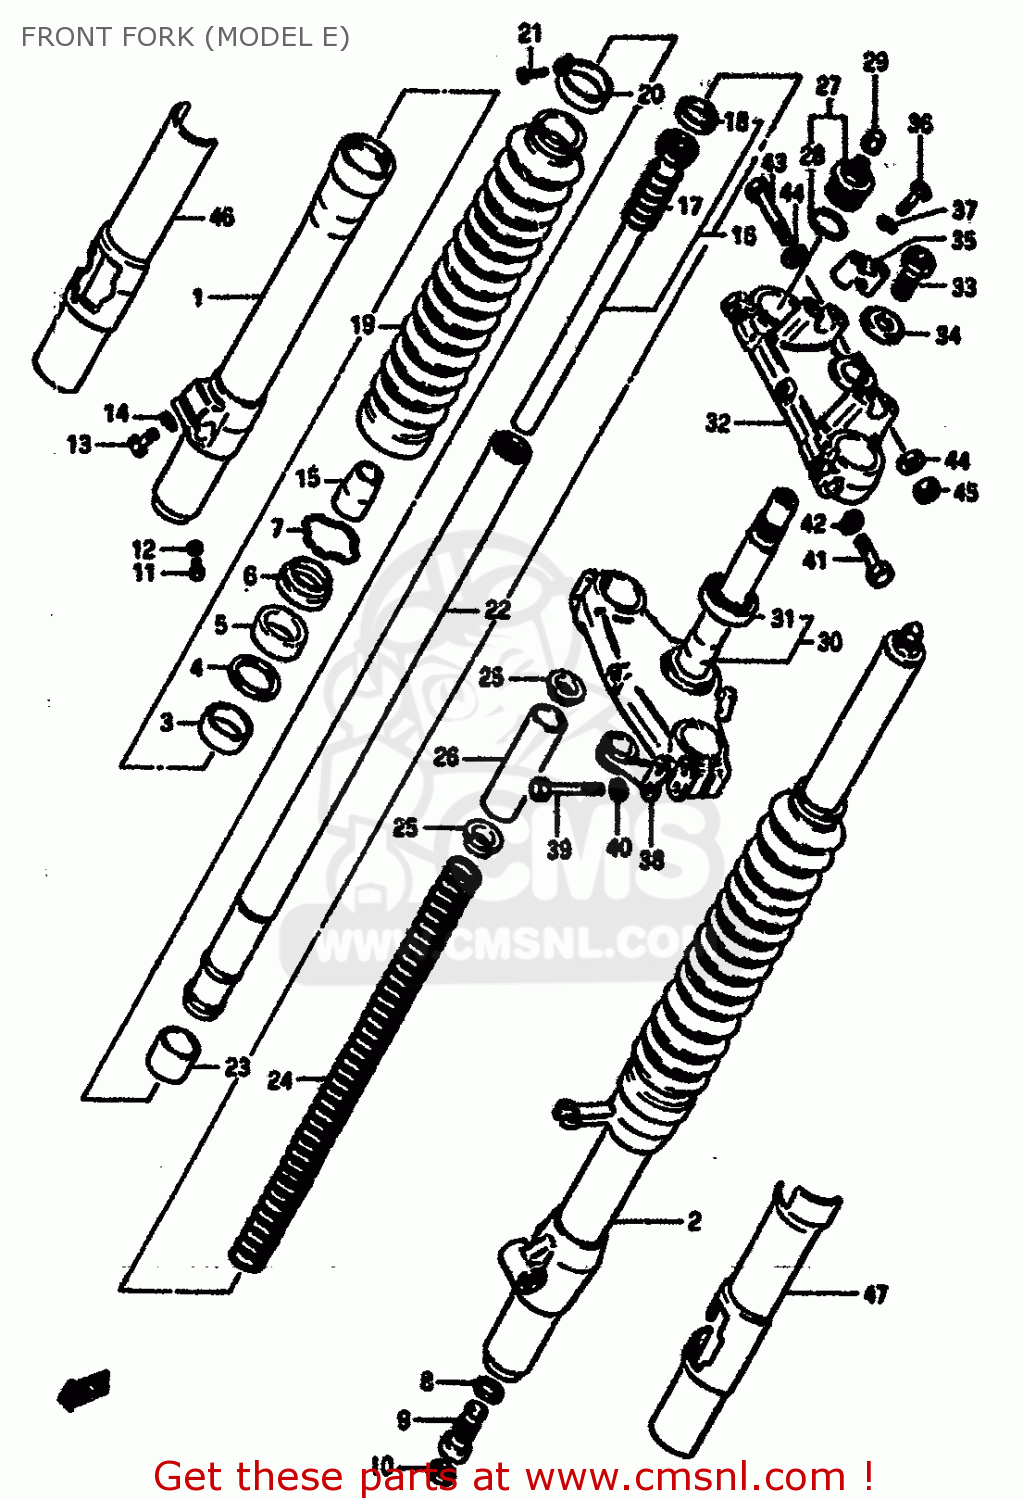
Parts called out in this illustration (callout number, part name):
1	TUBE,OUTER,RIGHT
2	TUBE,OUTER,LEFT
3	METAL,SLIDE
4	WASHER
5	SEAL,OIL
6	SEAL,DUST
7	RING,STOPPER
8	GASKET,FORK CYLINDER
9	VALVE,DF
10	CAP,FRONT FORK DF
11	SCREW 4X6
12	GASKET,DRAIN,PLUG (NAS)
13	BOLT (8X30)
14	WASHER,LOCK,8.
15	PIECE,FRONT FORK OIL LOCK
16	CYLINDER,FRONT FORK
17	SPRING,REBOUND
18	RING,FRONT FORK PISTON
19	BOOT,FRONT FORK COVER
20	BAND,BOOT,UPPER
21	SCREW 4X10
22	TUBE,FORK,INNER
23	PISTON
24	SPRING,FRONT FORK
25	GUIDE,FRONT FORK SPRING
26	SPACER,FRONT FORK SPRING
27	CAP,FORK INNER TUBE
28	O RING
29	CAP
30	STEM,STEERING
31	BEARING
32	HEAD,STEERING STEM
33	BOLT
34	WASHER
35	HOLDER,HANDLEBAR
36	BOLT
37	WASHER,LOCK,8.
38	GUIDE,CABLE
39	BOLT 8X40
40	WASHER,LOCK,8.
41	BOLT
42	LOCK WASHER
43	BOLT 8X50
44	WASHER
45	NUT
46	PROTECTOR,RIGHT
47	PROTECTOR
